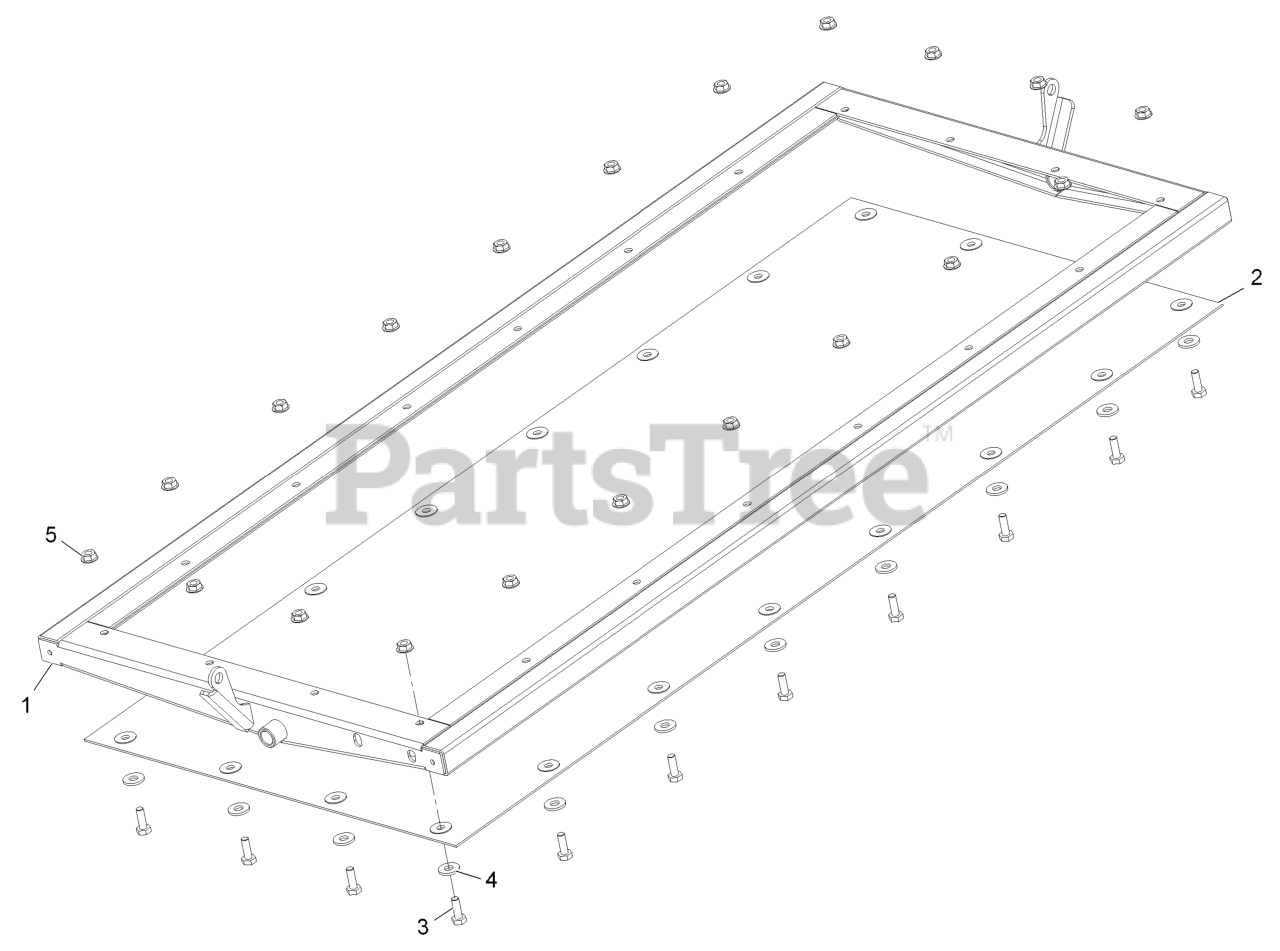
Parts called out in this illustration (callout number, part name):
1	DOOR-FRAME
2	SCREEN-DOOR
3	SCREW-HH
4	WASHER-FLAT
